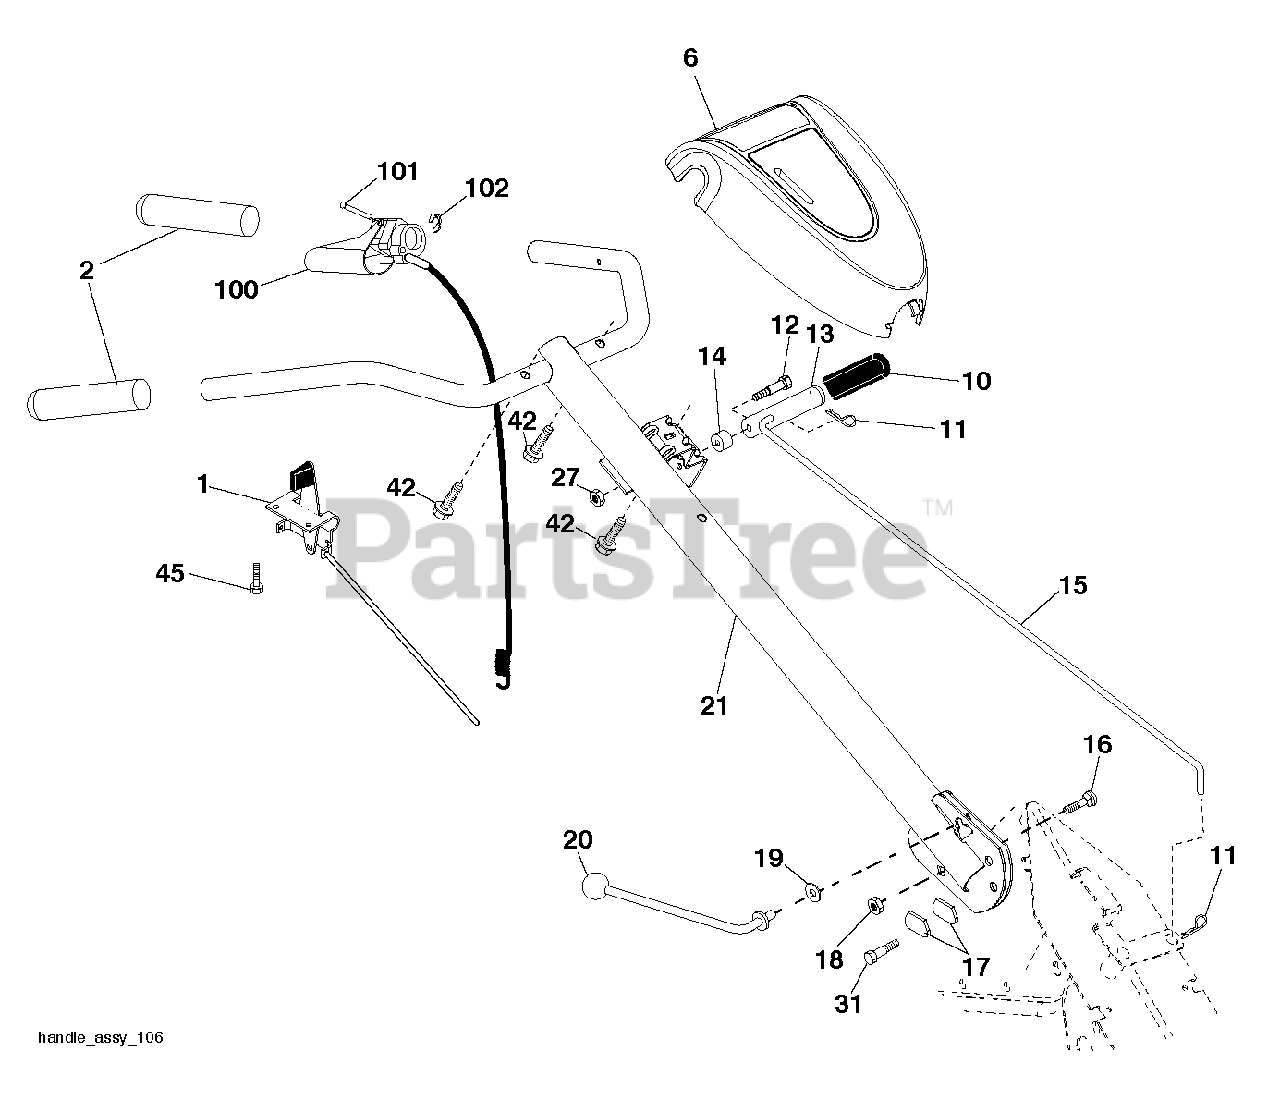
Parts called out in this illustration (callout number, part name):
1	CONTROL.THROTTLE.SNAP.IN
2	GRIP.1X5.06
10	GRIP T
11	RETAINER M
12	SHOULDER BOLT ST
14	GROMMET.RUBBER.CRT.TILLER
15	ROD, SHIFT
18	LOCKNUT
19	WASHER CRT
20	LEVER.LOCK.CRT
21	Curved Plow Handle Assembly for Tiller, Black
27	NUT T
31	BOLT.PIVOT
42	SCREW.#10 X 0.750.BOS THREAD
45	SCREW.#10 X 0.500
100	CONTROL.ASSEMBLY.TINE.TILLER
101	PIN, PIVOT
102	RETAINING RING
